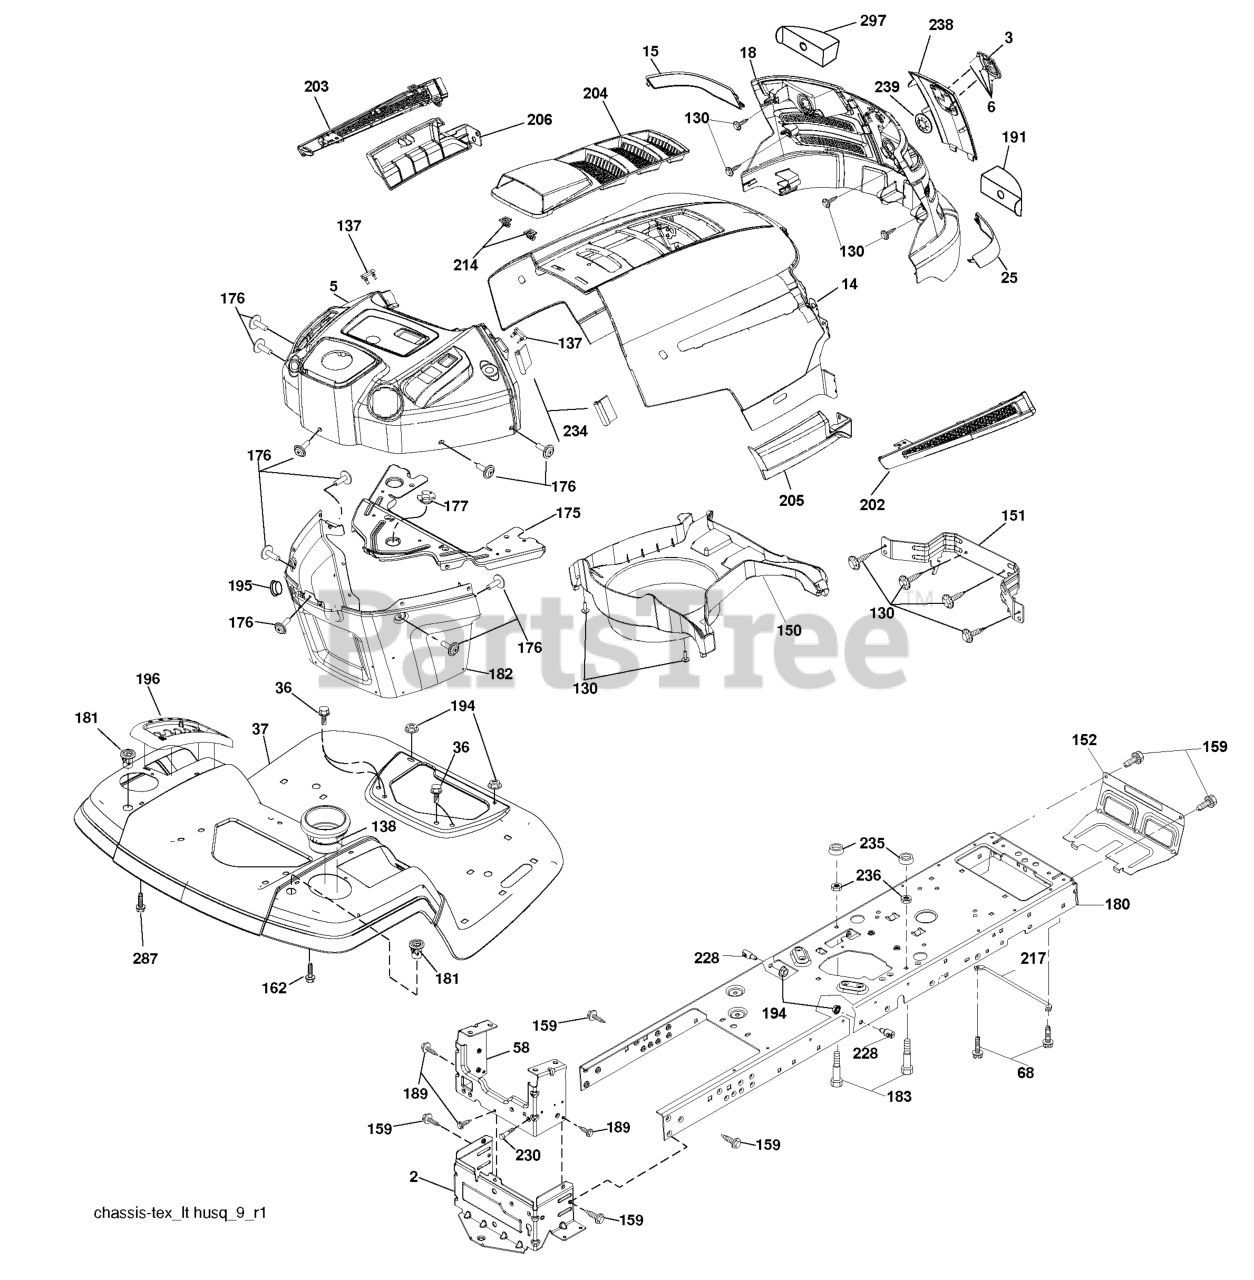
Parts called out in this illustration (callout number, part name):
2	Drawbar Lower
3	Logo
5	Dash
14	Hood
15	Lens LH
18	Grille
25	Lens RH
36	Screw 5/16-18 x 3/4
37	Fender
58	Drawbar Upper
68	Screw THDROL 5/16-18 x 1/2
130	Screw #10 x 0.750
137	Bumper Dash
138	Cupholder
151	Bracket Pivot
152	Shield Browning
159	Screw 3/8-16 x 3/4
175	Crossmember
176	Screw 10-24 x 5/8
177	Bushing Steering
180	Chassis
181	Bushing Mtg. Fender Crgo
182	Dash Lower
183	Bolt 5/16-18 unc x 1-1/4
189	Screw 5/16-18 x 3/4
191	Insert Reflective RH
194	Nut Lock Hex Flange 5/16-18
195	Plug Dash
196	Console Asm. Deck Lift
202	Vent Side Hood RH
203	Vent Side Hood LH
204	Vent Top Hood
205	Skirt Side RH
206	Skirt Side LH
214	Clip Retainer
217	Rod Pivot Hood
228	Stud Fastener
234	Bumper Hood
235	Spacer Fender
236	Nut Lock 5/16-18 unc
238	Trim
239	Clip Tinnerman
287	Screw 1/4-20 x 3/8
297	Insert Reflective LH
